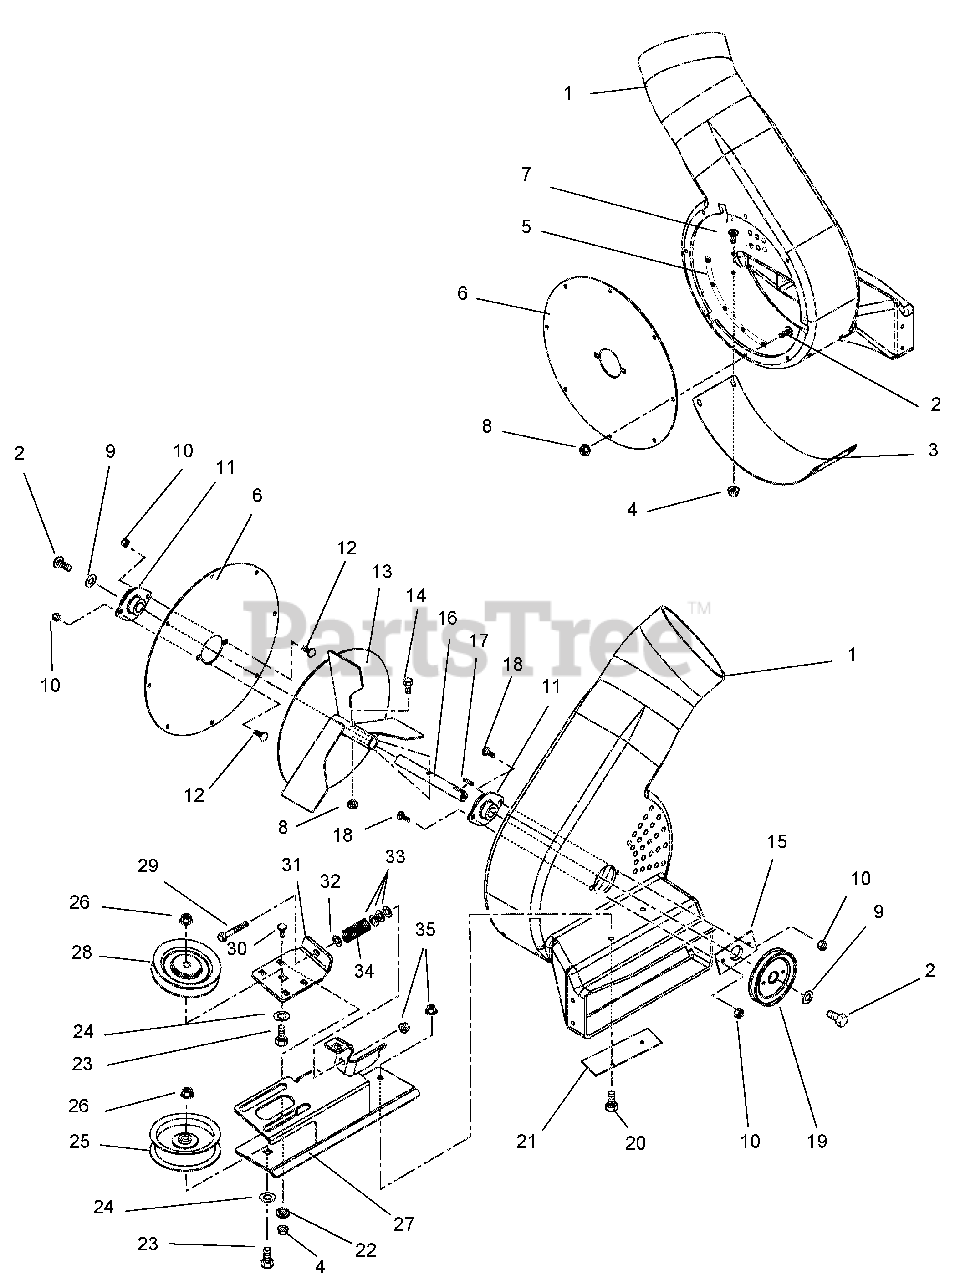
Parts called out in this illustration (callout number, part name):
1	BLOWER (SERVICE ASSEMBLY)
2	BLT-HEX .25-20X.50 GR5 EPOXY
3	PLATE, SKID
4	@NUT-LK-TOP-FLG .25-20 YWZC
5	MTG BOLT REINFORCING PLT - BLK
6	PLATE, BEARING MOUNT
7	SCR-MCH .25-20X.75 TXTR YWZC
8	@NUT-LK-NYL-FLG .25-20 YWZC
9	WSHR-FL-STL .344X1.125X.135
10	@NUT-LK-NYL .312-18 YWZC
11	BEARING, 2 BOLT FLANGE -.75 ID
12	@BLT-RHDSSQNK .31-18X.62 G5YZ
13	WELDMENT, IMPELLER, 3 BLADE
14	@BLT-HEX .25-20X1.50 GR5 YWZC
15	BEARING WASHER PLATE - BLK
16	SHAFT, IMPELLER
17	KEY-SQ .187 X .50 X .187
18	BLT-RDHDSQNK.31-18X.88 GR5YWZC
19	SHEAVE, BLOWER - 4.25 DIA.
20	BOLT-HEX.31-18X.875 YWZC GR5
21	PLATE,BACK
22	BSHG-FLG .265X.437X.250X.750
23	@BLT-HEX .38-16X1.75 GR5 YWZC
24	@WSHR-FL-STL.406X.812X.065 YWZ
25	IDLER FLANGED 3.50
26	@NUT-LK-TOP-FLG .38-16 YWZC
27	WELDMENT, IDLER MOUNT
28	V-IDLER, 4.00X.38
29	@BLT-HEX .31-18X4.00 GR5 YWZC
30	@BLT-RDHDSQNK .25-20X.75 G5YZ
31	BRACKET, ADJUSTABLE IDLER
32	NUT-PUSH .312
33	WSHR-FL-STL .406X1.00X.188 YWZ
34	SG-COMP .092X.77X3.13 WLD 36
35	@NUT-LK-TOP-FLG .31-18 YWZC
36	BLOWER (SERVICE ASSEMBLY)
